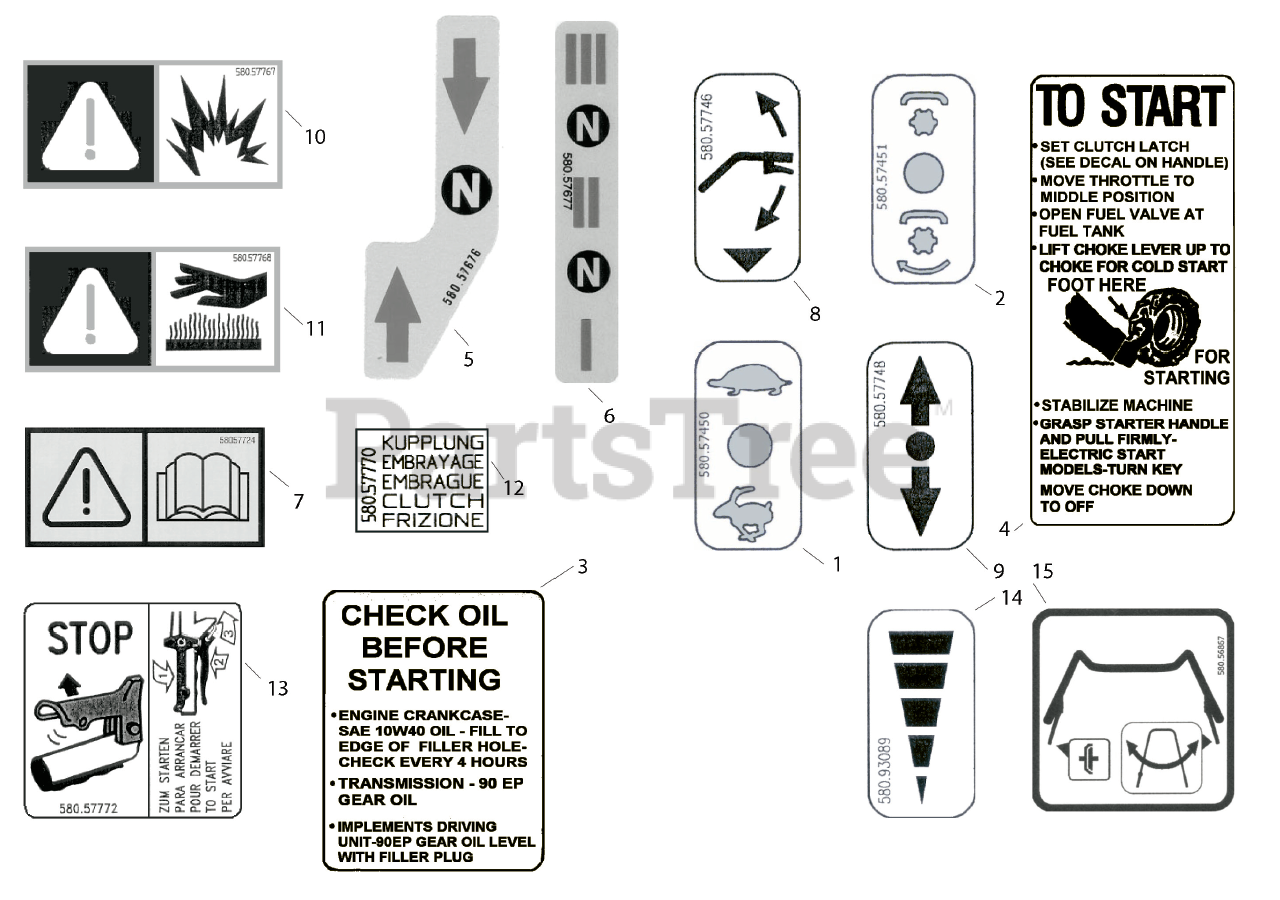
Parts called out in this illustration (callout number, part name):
1	DECAL, THROTTLE
2	DECAL
3	DECAL, CHECK OIL
4	DECAL, TO START
5	DECAL, NEUTRAL
6	DECAL, GEAR SELECT
7	DECAL, READ OP. MANUAL
8	DECAL, HEIGHT ADJ.
9	DECAL, FWD/REVERSE
10	DECAL
11	DECAL
12	DECAL, CLUTCH
13	DECAL, OPERATOR PRESENCE
14	DECAL
15	DECAL, HANDLE PIVOT
